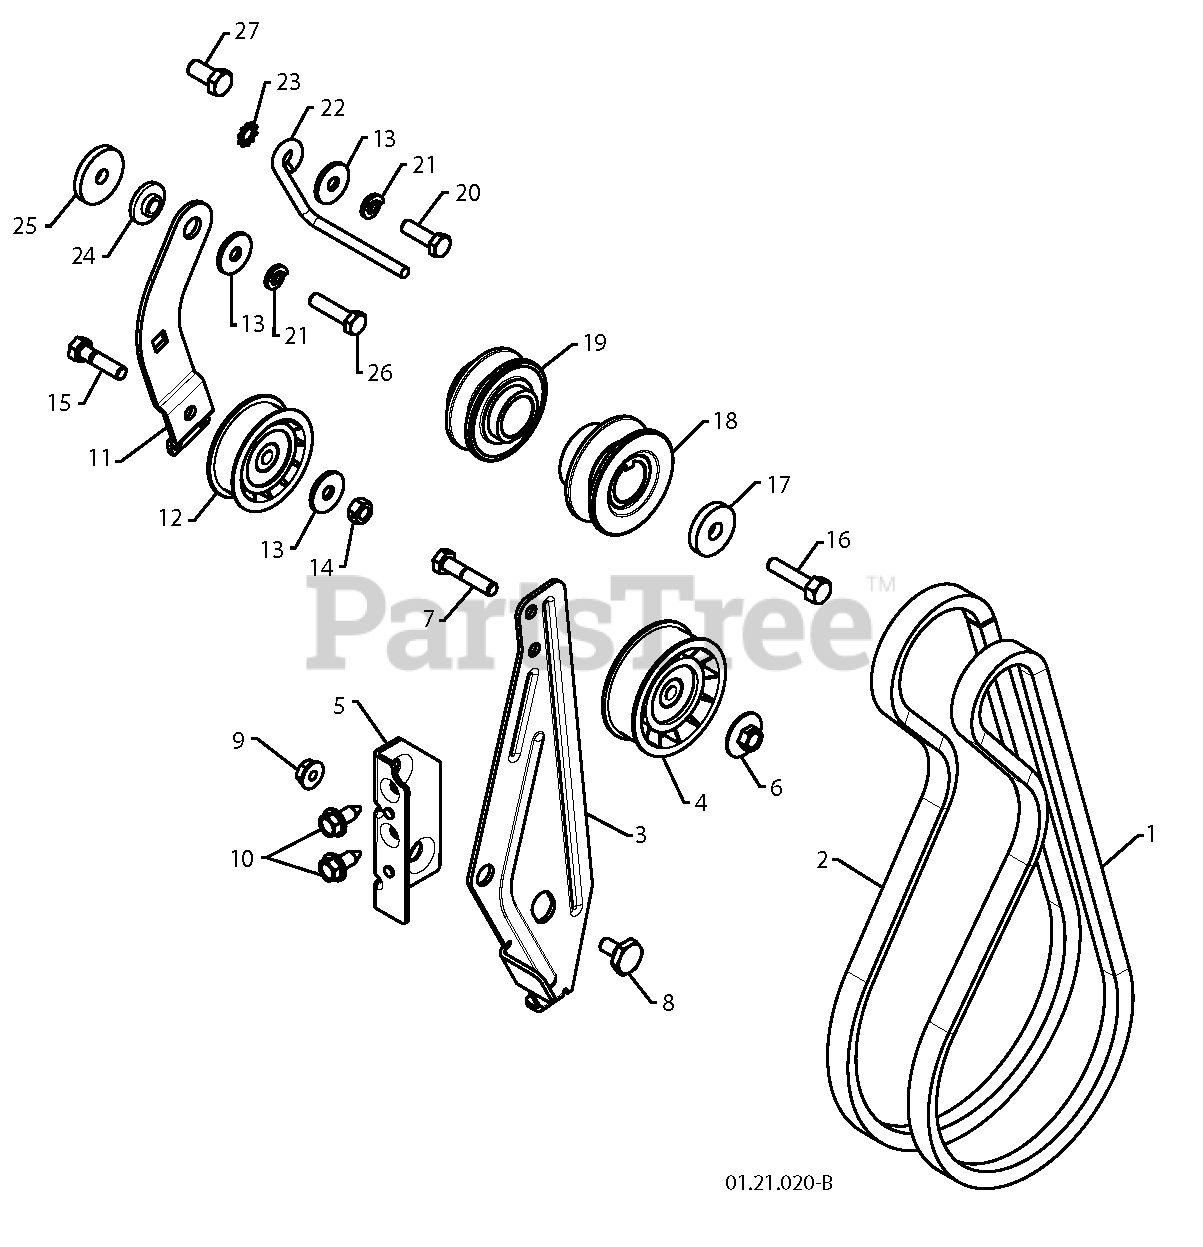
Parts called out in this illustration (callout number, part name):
1	V-BELT.IMPELLER
2	TRACTION BELT
3	RP ARM.IDLER.BRAKE.
4	PULLEY.W/SPACER.2.75
5	RP BRACKET.IDLER.PIVOT
6	NUT.FLANGE.HEX.5/16X18.BLACK
7	HEX BOLT
8	BOLT.SHOULDER.1/2X12
9	NUT.LOCK.5/16-18
10	BOLT.5/16HEX.WHS.HD
12	PULLEY.W/SPACER.2.25
13	STEEL WASHER
14	NUT.71038.31-18.HEX.NYLOCK
15	BOLT.5/16-18X1-1/4 FULL.THREAD
16	SCREW, HEX HD 3/8-24 X 1-3/8
17	WASHER.400X1.25X5.
18	PULLEY ENG IMPELLER
19	PULLEY.ASM.ENG.TRACTION.1.00
21	LOCKWASHER
22	Belt Guide, RH
24	BUSHING, IDLER PIVOT
25	WASHER.FLAT.34X1.38X22
26	CAPSCREW.HEXHD.5/16X1.25.
27	SCREW.3/8-16 X .750
